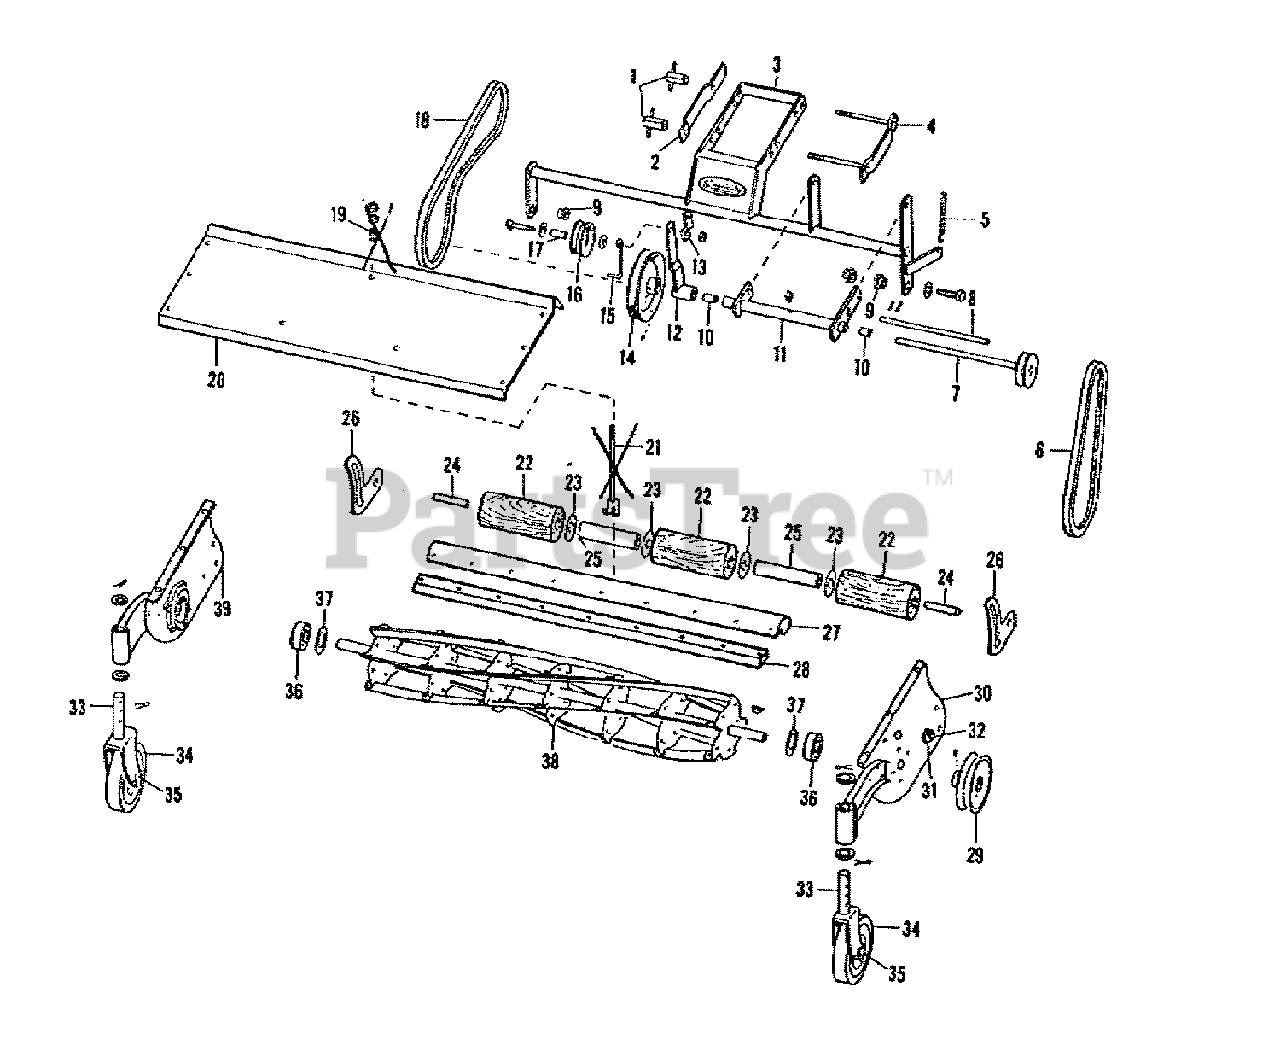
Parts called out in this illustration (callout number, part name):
1	T-NUT, Complete
2	PLATE, Hitch Side
3	ARM ASSEMBLY, Push
4	CLAMP ASSEMBLY, Hitch
6	"V" Belt, Reel, 30" Long
7	SHAFT ASSEMBLY, Pulley
8	ROD, Pivot
11	HOUSING ASSEMLBY, Brg.
12	LEVER ASSEMBLY, Idler
13	BRACKET, Lever
15	STOP, Belt
16	PULLEY ASSEMBLY, Idler
17	RACE, Inner Brg.
18	V-BELT, 40"
19	SPRING
21	HOOK ASSEMBLY, Cutter Bar
22	ROLLER (3 Required)
23	WASHER, Roller
24	ROLLER, Shaft
25	SPACER, Roller
26	BRACKET, Roller
27	CUTTER, Bar
28	CUTTER BAR BLADE, W/ Rivets
29	SHEAVE, Reel
30	FRAME, Side, L.H.
31	ADJUSTING CAM
33	CASTER YOKE ASSEMBLY
34	CASTER, Wheel w/ Bearings
35	CASTER, Axle
36	BALL, Bearing
37	REEL, Bearing Washer
38	REEL ASSEMBLY, 30"
39	FRAME, Side, R.H.
